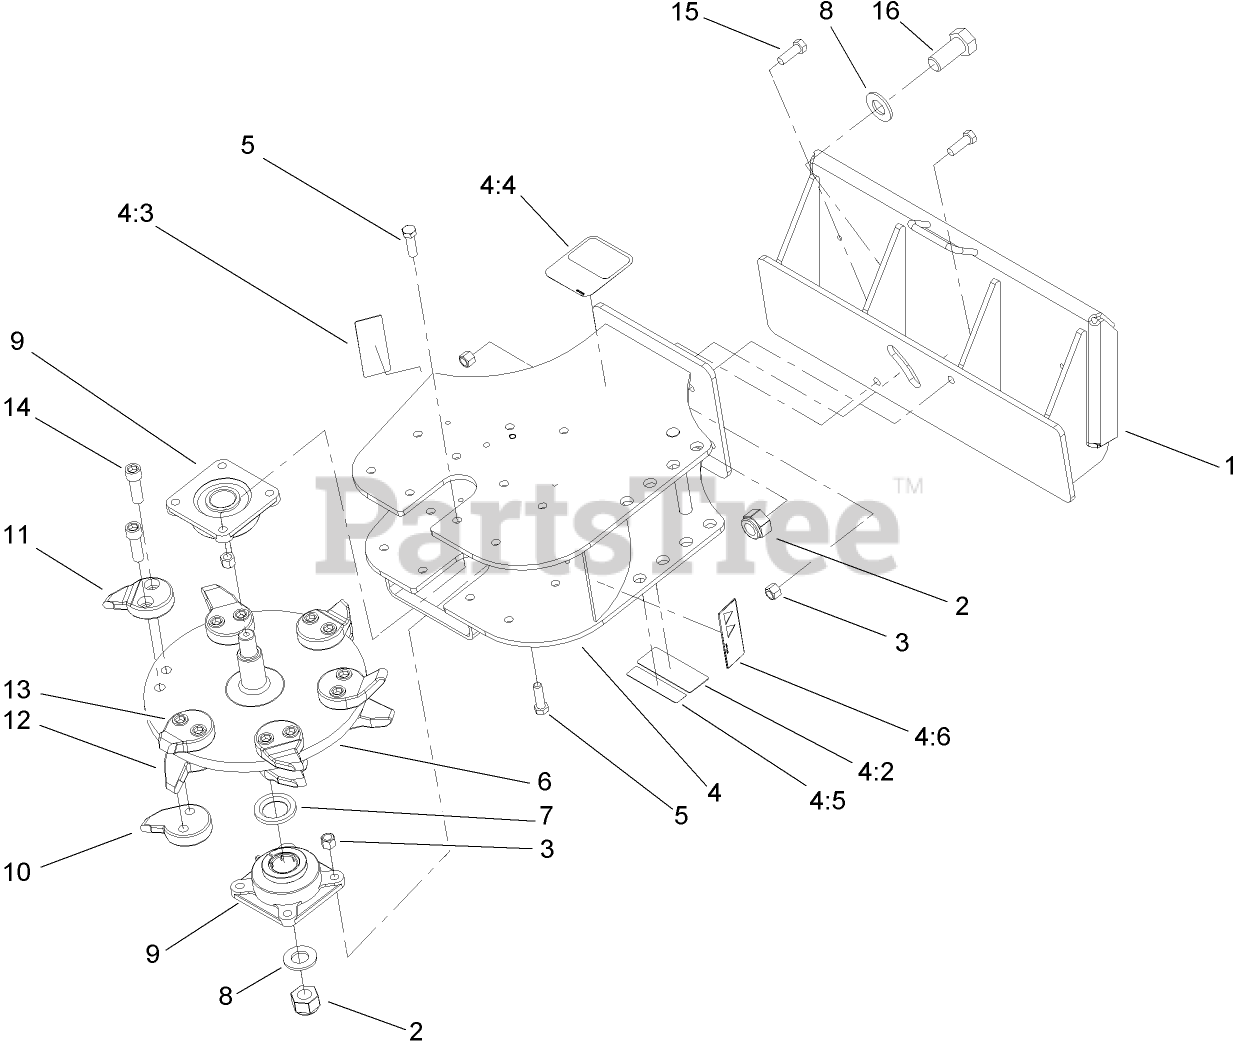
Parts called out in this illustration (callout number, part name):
1	QUICK ATTACH ASM
2	NUT-HEX, NI
3	NUT-LOCK, NI
4	GRINDER FRAME ASM
4:2	DECAL-WARNING
4:3	DECAL-DANGER
4:4	DECAL
4:5	DECAL-WARNING
4:6	DECAL-WARNING
5	SCREW-HH
6	WHEEL-CAST
7	WASHER-BEARING
8	WASHER-FLAT
9	BEARING
10	TOOTH-STR, THREADED
11	TOOTH-STR,CBORED
12	TOOTH-CURVED,THREADED
13	TOOTH-CURVED,CBORED
14	SCREW-HSH
15	SCREW-HH
16	SCREW-CAP
